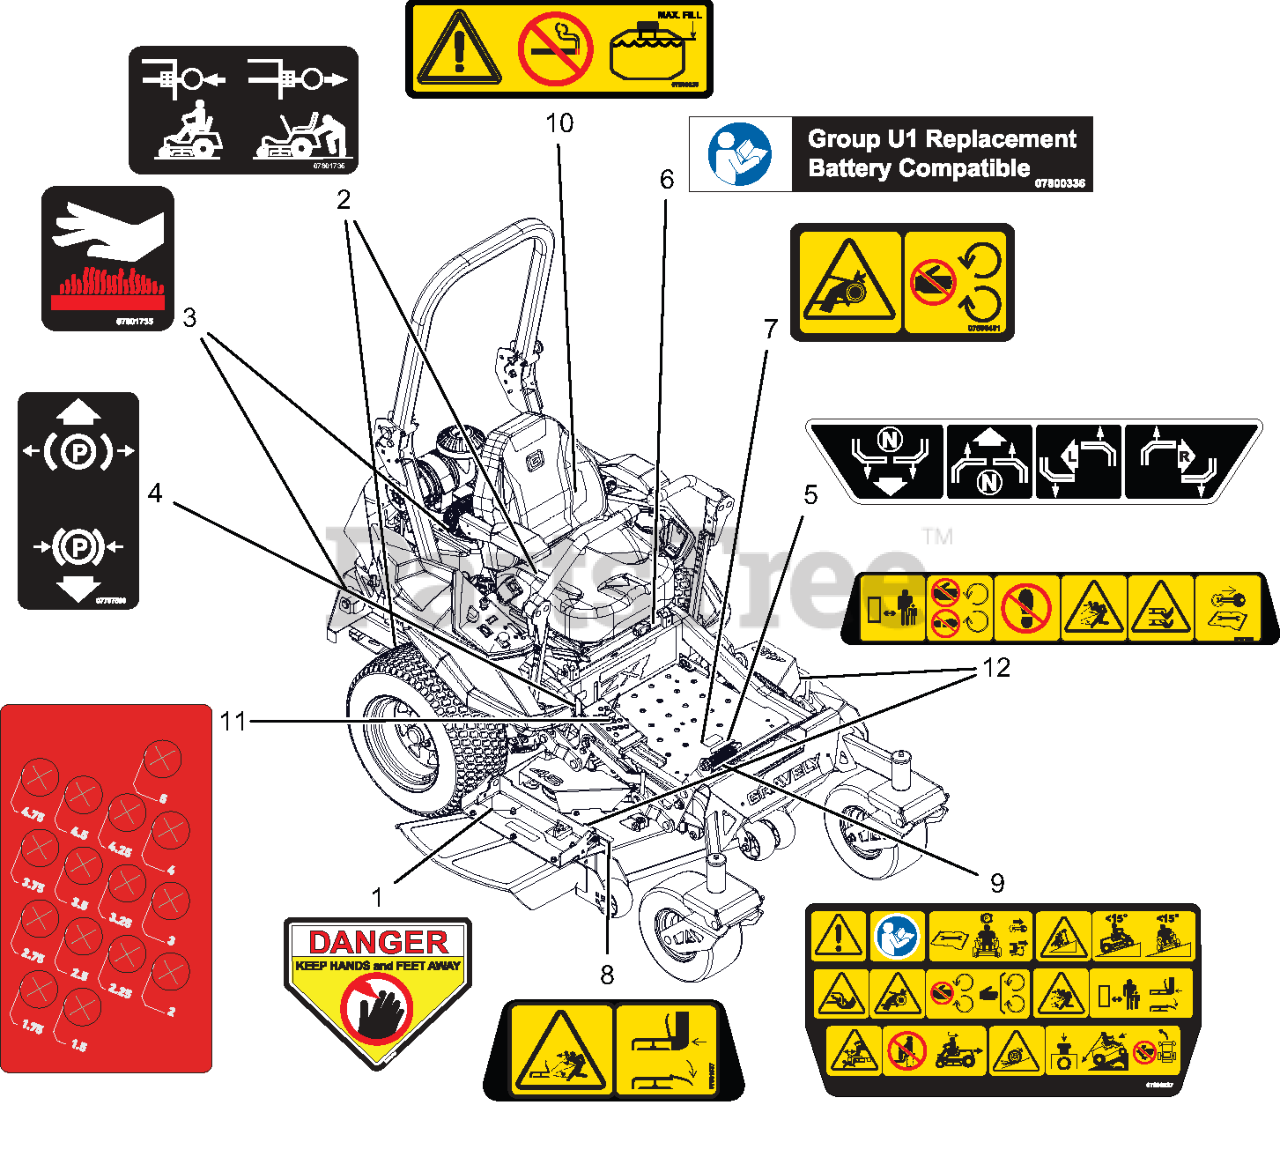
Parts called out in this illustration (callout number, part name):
1	DECAL, DANGER
2	DECAL,TRANSAXLE DISCONNECT
3	DECAL,SAFETY HOT SURFACE
4	DECAL, PARKING BRAKE LEVER
5	DECAL- INSTRUCTIONAL-STEERING
6	DECAL, U1 BATTERY REPLACEMENT
7	DECAL, SAFETY - GUARDING
8	DECAL- SAFETY - DECK GUARDING
9	DECAL, MAIN SAFETY
10	DECAL, FUEL WARNING
11	DECAL, HEIGHT OF CUT
12	DECAL- SAFETY - MOWER DECK
